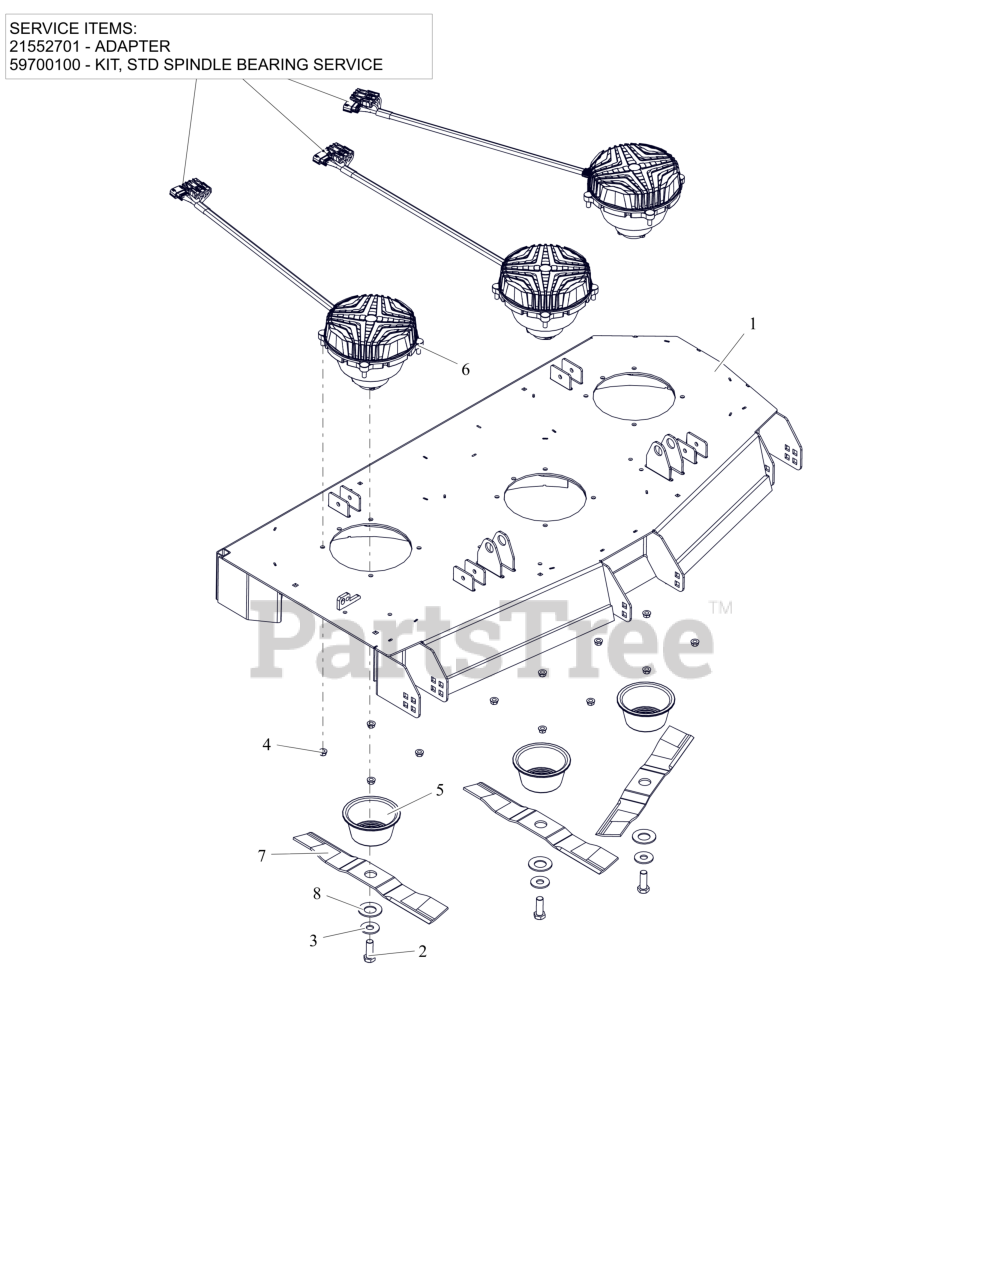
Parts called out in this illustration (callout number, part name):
1	KIT,DECK 52 SD W/DECALS-G
2	BLT, HEX .62-18X1.75 G8 ZCC
3	WSHR, HRDN 0.687X1.75X0.134 HRD
4	NUT-LK-CTR-FLG .375-16 GF ZCC
5	GUARD, SPINDLE LOWER
6	MOTOR, DECK - 48"/52" CW
6	ADAPTER
6	KIT,STD SPINDLE BEARING SERVICE
7	BLADE- MOWER-18.00" LOW
8	WSHR, BLVL - .56X28.5X3 PHOS.COAT
